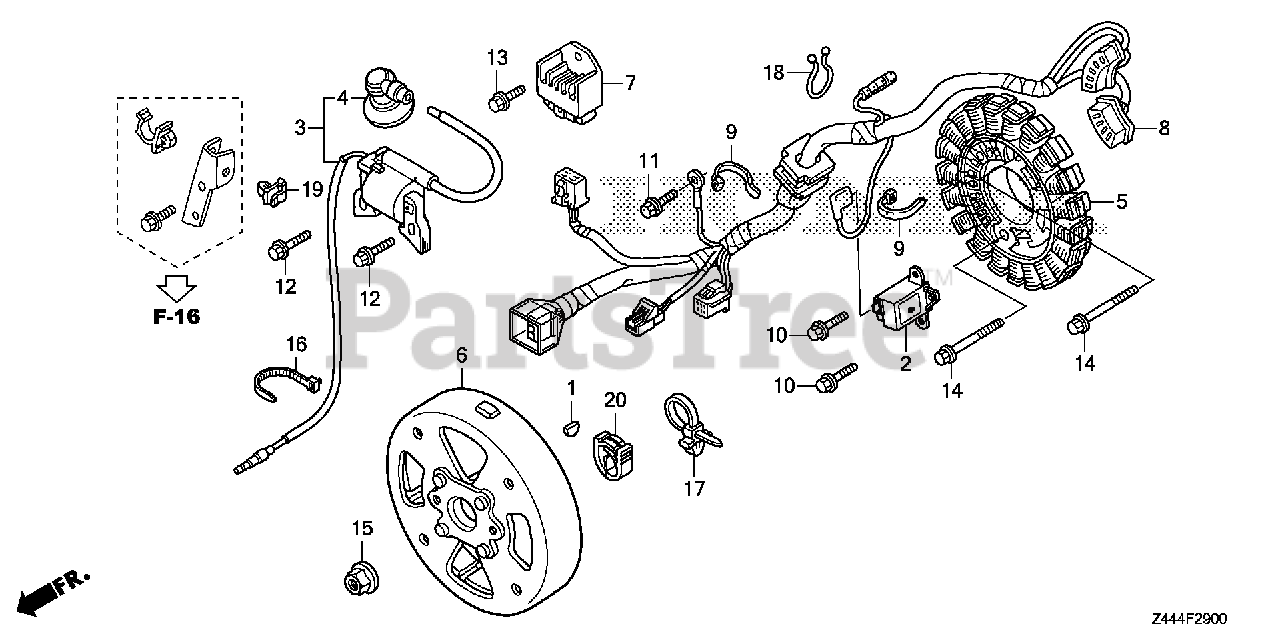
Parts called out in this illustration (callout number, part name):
1	KEY, SPECIAL WOODRUFF (25X18)
2	GENERATOR, PULSE
3	COIL ASSY., IGNITION
4	CAP ASSY., NOISE SUPPRESSOR
7	RECTIFIER ASSY.
8	WIRE HARNESS ASSY., GENERATOR
9	BAND, NYLON
10	BOLT, FLANGE (5X14) (CT200)
11	BOLT, FLANGE (5X10)
12	BOLT, FLANGE (6X20) (CT200)
13	BOLT, FLANGE (6X16)
14	BOLT, FLANGE (5X35)
15	NUT, SPECIAL (14MM)
16	BAND, HARNESS (BLACK)
17	BAND, WIRE HARNESS (150MM) (Honda Code 1352103). (BLUE)
18	BAND, TUBE
19	CLIP, WIRE HARNESS
20	CLIP, WIRE HARNESS
